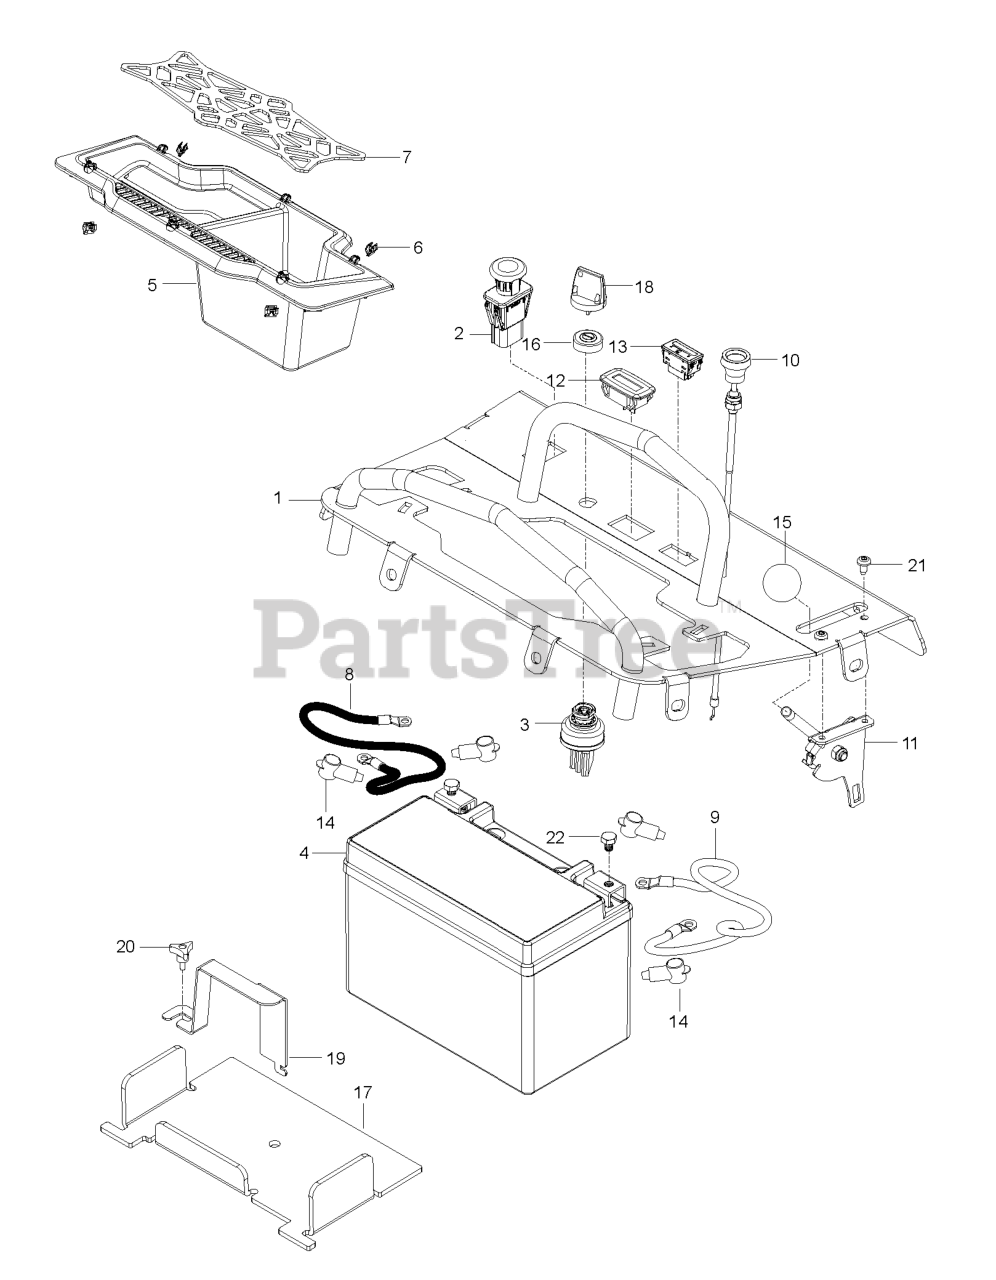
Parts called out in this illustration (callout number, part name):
1	CONTROL PANEL WELDMENT
2	SWITCH.PTO.10AMP.SEALED.6P.SPS
3	SWITCH, IGNITION, INDAK
4	BATTERY.STARTER.AGM.LEOCH.8AH
4	Brackets
5	TRAY.STORAGE.MS428
8	PRIMARY CABLE STAND ON SINGLE
9	PRIMARY CABLE STAND ON SINGLE
10	CABLE, CHOKE, 38
11	THROTTLE, KAWASAKI 33"
12	GUAGE.SRVCMNDR.HRMTR.
13	LED.SMALL.FUEL.LEVEL.V500
15	KNOB - SHIFT
16	CAP IGNITION NUT
17	PAD BATTERY TEMP ISOLATION, ST
18	KEY, IGNITION
19	STRAP.PNT.BATTERY.HOLD.DOWN.GY
20	KNOB W/STUD
21	SCREW T-30 1/4-20 X
22	SCREW M6 X 8MM HEX CAP
